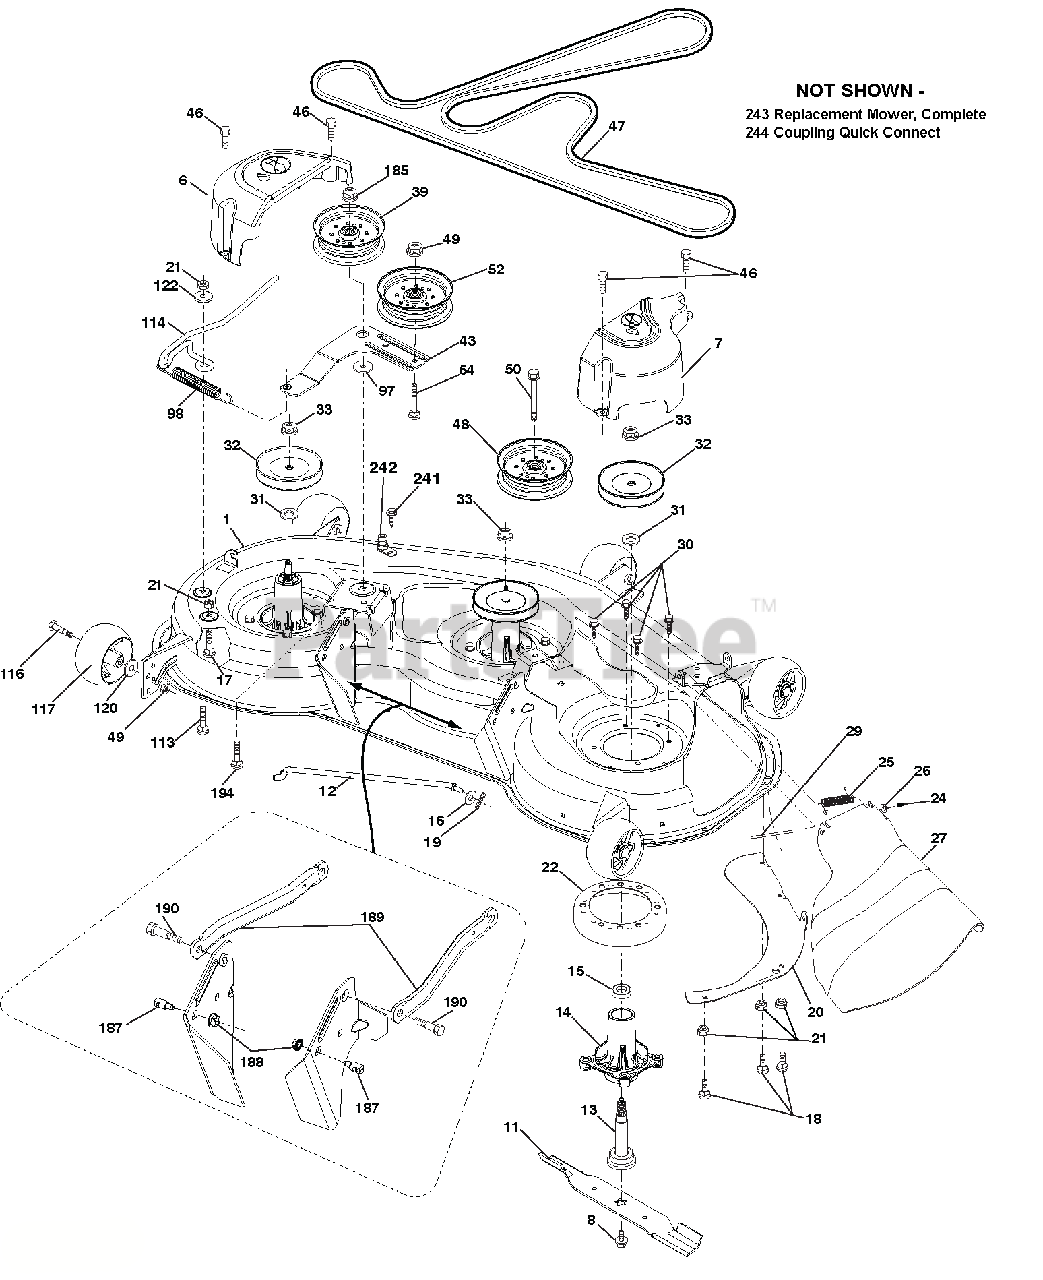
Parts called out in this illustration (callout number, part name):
1	DECK.WELDMENT.48"MS-422
6	COVER MANDREL LH
7	COVER MANDREL RH
8	BOLT/WASHER ASM.7/16-20.UNF
11	48" BAGGER BLADE
11	BLADE, MULCH 42" 16.75"
12	ROD.ANTI SWAY.48/54"K46.TEX
13	SHAFT ASM.MANDREL.48/54"SVC
14	HOUSING.MANDREL.4PT.SERVICE
15	BEARING.BALL.MANDREL
16	Washer 13/32 x 13/16 x 12 Ga.
17	BOLT.CARR.5/16-18 X 5/8 SHORT
18	BOLT.RDHD.SQNK.5/16-18 X 5/8
19	PIN.COTTER.5/16.BOW TIE LOCK
20	BAFFEL VORTEX
21	Nut, Hex, Crownlock 5/16-18
22	STRIPPER.MANDREL.DECK
24	CAP.SLEEVE..80X.112.BLK.MOWER
25	SPRING.TORSION.48"
26	NUT.PUSH.PHOS.& OIL
27	DEFLECTOR SHIELD
29	ROD.HINGE.42/46"
30	SCREW.THD ROLL.DOD PT.HEX
31	WASHER.SPACER.MANDREL
32	PULLY, MANDREL
32	MANDREL ASM.48/54"
32	(KEY #14), SHAFT ASSEMBLY (KEY #13) AND
32	WASHER AND BLADE BOLT/WASHER NOT
32	INCLUDED.)
33	NUT.FLANGE.LOCK.TOP
39	PULLEY.IDLER.4.50.HUB.SPECIAL
43	ARM.ILDER
46	SCREW.THD.ROLL.1/4-20 X 5/8
47	PRIMARY MOWER BELT 48"
48	PULLEY.IDLER.4.50.RAW
49	Nut, Hex, Flangelock 3/8-16
50	BOLT RDHD SQNK 3/8-16 UNC X 2
52	PULLEY.IDLER 48"PRIMARY
54	BOLT.CARR.SH.3/8-16X1-1/2.GR5
97	WASHER.FLAT.HARDENED
98	SPRING.DRIVE.DECK.2006
113	BOLT.CARR.5/16-18UNC X 1
114	ROD TENSION RELIEF
116	BOLT.SHOULDER.3/8-16X3-5/8.GR5
117	WHEEL.GAUGE.RALLY.
120	WASHER.13/32 X 1-1/4 X 12 GA.
122	BUSHING.RELIEF.TENSION
185	NUT.LOCK.FLANGE.7/16-14.GR5
187	STUD.FASTNER.W/'D'ANTI-ROTATIO
188	Nut, Lock Hex Flange 5/16-18 u
189	ARM.SUSPENSION.MOWER.REAR
190	BOLT.SHOULDER
194	BOLT CARR SQNK 3/8-16 X 2-1/4
242	PORT WASHOUT
243	REPLACE MOWER, COMPLETE
244	COUPLING QUICK CONNECT
